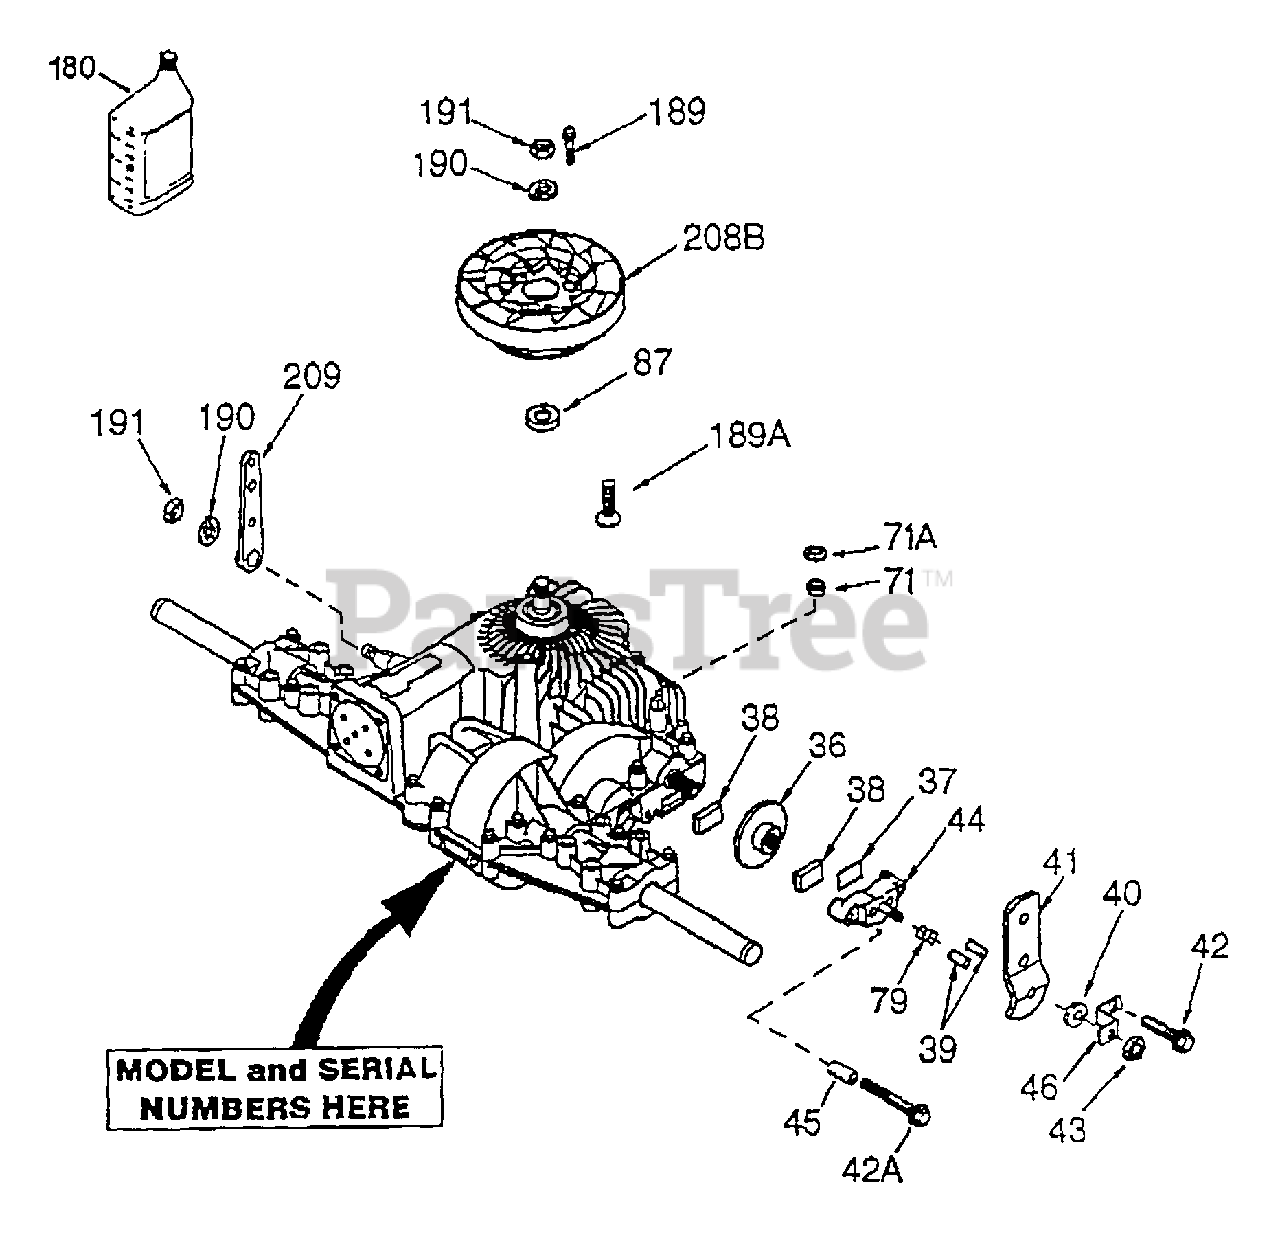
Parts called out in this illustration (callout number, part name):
36	Brake Disc (Peerless part number)
37	Brake Pad Plate (Peerless part number)
38	Brake Pad (Peerless part number) (AYP part number)
39	Dowel Pin (Peerless part number)
40	Flat Washer (Peerless part number)
41	Brake Lever (Peerless part number)
42	Screw, 1/4-20 x 1-1/4" (Peerless part number)
42A	Screw, 1/4-20 x 2-1/4" (Peerless part number)
43	Locknut, 5/16-24 (Peerless part number)
44	Brake Pad Holder (Peerless part number)
45	Spacer (Peerless part number)
46	Brake lever Bracket (Peerless part number)
71	Square Cut Ring (Peerless part number)
71A	Pushnut, 9/16" (Peerless part number)
79	Spring (Peerless part number)
87	Oil Seal, 5/8" (Peerless part number)
180	Gear Oil 80W90 (AYP part number)
189	Drive Screw #6 x 1/2" (Peerless part number)
189A	Screw, 10-32 x 1/2" (Peerless part number)
190	Lockwasher (Peerless part number)
191	Nut, 7/16-20 (Peerless part number)
208B	Fan/Coupling (Peerless part number)
209	Control Lever (Peerless part number)
